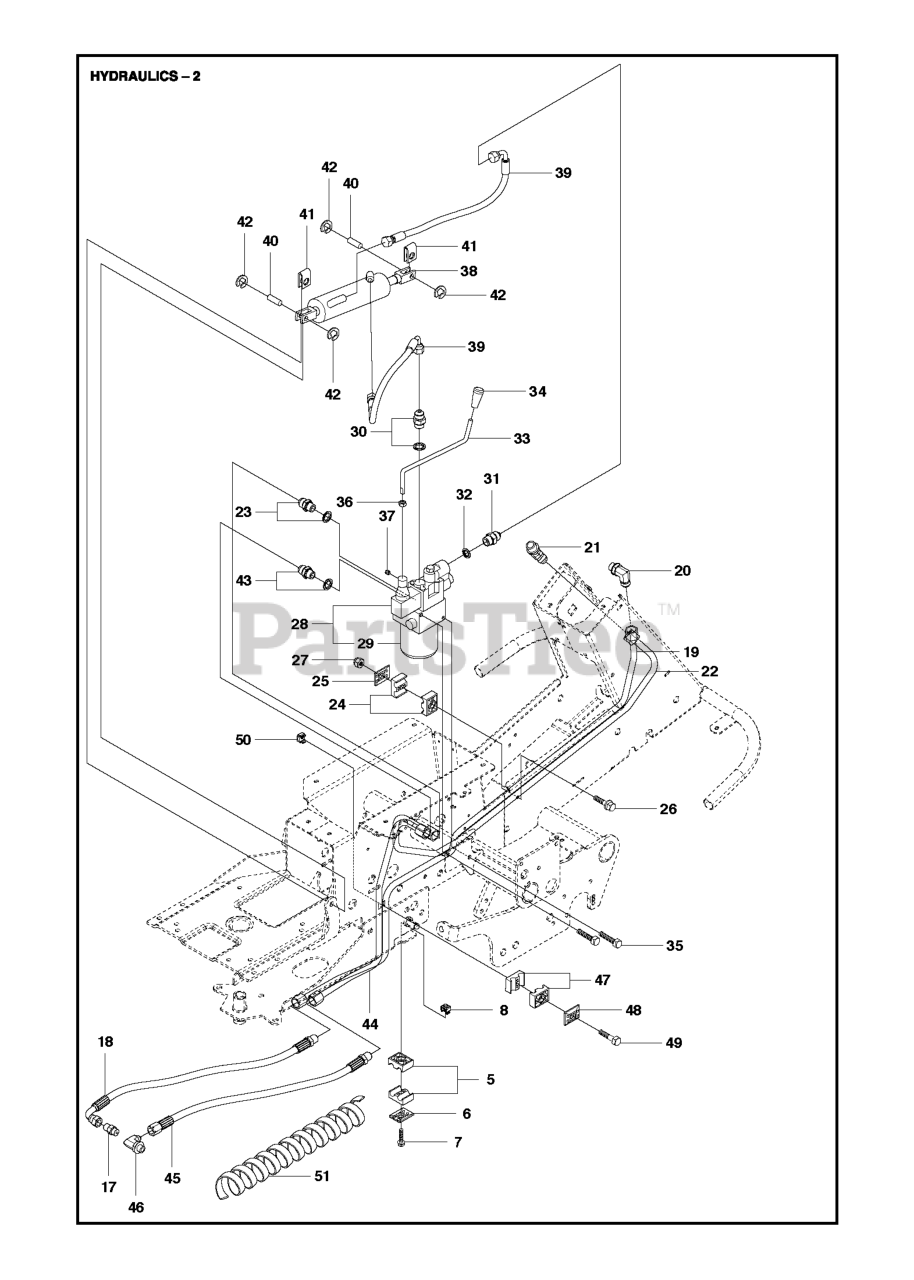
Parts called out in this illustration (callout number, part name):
5	PIPE CLAMP
6	COVER PLATE
7	SCREW EHHFM
24	PIPE CLAMP
27	LOCKNUT M6
29	FILTER
35	REPL BY 725 24 49-51
36	NUT
42	RETAINING RING SGA 10
47	PIPE CLAMP
51	HOSE GUARD D=43 L=400
